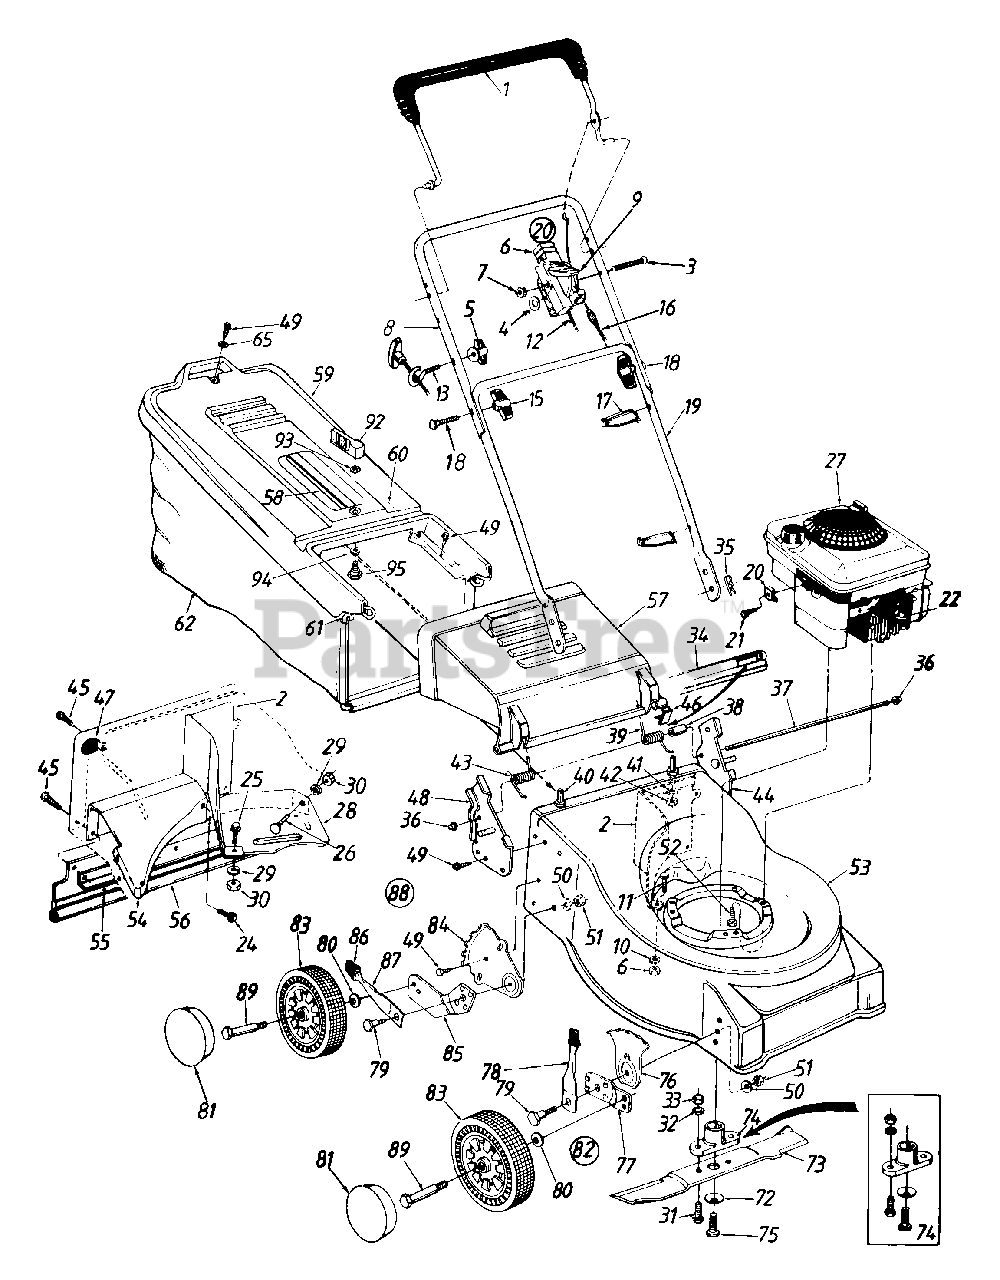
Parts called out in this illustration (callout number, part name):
1	Control Handle Ass'y.
4	Spr. Wash..66" I.D.
5	Wing Nut 1/4-20 Thd.
6	Throttle Body
7	Hex L-Nut 1/4-20 Thd.
10	Bell-Wash. 1/4" I.D.
11	Hex Bolt 1/4-20 x .85"
12	Throttle Control Wire - 55"
13	Rope Guide
15	Hand Knob
16	Control Cable - 40.5"
17	Cable Tie
18	Curved Hd. Bolt 5/16-18 x 2" Lg.
20	Throttle Box Comp.
21	Hex Self-Tap Scr. #10-32 x .62" Lg.
22	Spark Plug Boot
24	Hex B-Tap Scr. 1/4 x .38" Lg.
25	Hex Bolt 1/4-20 x .85" Lg.
26	Carriage Bolt 1/4-20 x .5" Lg.
27	Engine
28	Baffle
29	L-Wash. 1/4" I.D.
30	Hex Nut 1/4-20 Thd.
31	Hex Bolt 3/8-24 x 1" Lg.
32	L-Wash. 3/8" I.D.
33	Hex Nut 3/8-24 Thd.
34	Seal - Extrusion
35	Int. Cotter Pin 5/16" Dia.
36	Cap Speed Nut
37	Hinge Pin 17.75" Lg.
38	Spacer .255" I.D.
39	Torsion Spring - L.H.
40	Shld. Pin 3/8-24 x 1.43" Lg.
41	L-Wash. 3/8" I.D.
42	Hex Jam Nut 3/8-24 Thd.
43	Torsion Spring - R.H.
46	Deflector Plug
47	Corner Plug
48	Handle Brkt Ass'y - R H
49	Hex L-Wash. AB-Tap Scr. 1/4 x 62" Lg.
50	Bell-Wash .39" I.D
51	Hex Nut 3/8-16 Thd.
52	Hex L-Wash. Hd. Scr 3/8-16 x 1" Lg.
57	Rear Chute Deflector
58	Hardtop Handle
59	Hardtop Bag Cover
60	Rear Catcher Frame
62	Grass Bag
65	Fl-Wash..281" I.D.
72	Bell-Wash..46" I.D.
73	21" Blade
74	Blade Adapter Kit
75	Hex Bolt 7/16-20 x 1.5" Lg.
76	Height Adj. Plate
78	Spring Lever Ass'y w/Knob
79	Shld. Bolt 50" Dia. x 357"
80	Bell-Wash..38" I.D. x 88" O.D.
81	Hub Cap
82	Height Adj. Ass'y. Comp - R H
83	Wheel Ass'y. Comp.
84	Index Plate
85	Pivot Bar - R.H.
86	Spring Lever Knob
87	Spring Lever
88	Rear Height Adj. Ass'y Comp.- R.H.
89	Axle Bolt
92	Grass Catcher locking Knob
93	Internal L-Wash. 1/4" I.D.
94	Wave Washer 3/8" I.D.
95	Shld. Bolt .342" Dia. x .268"
